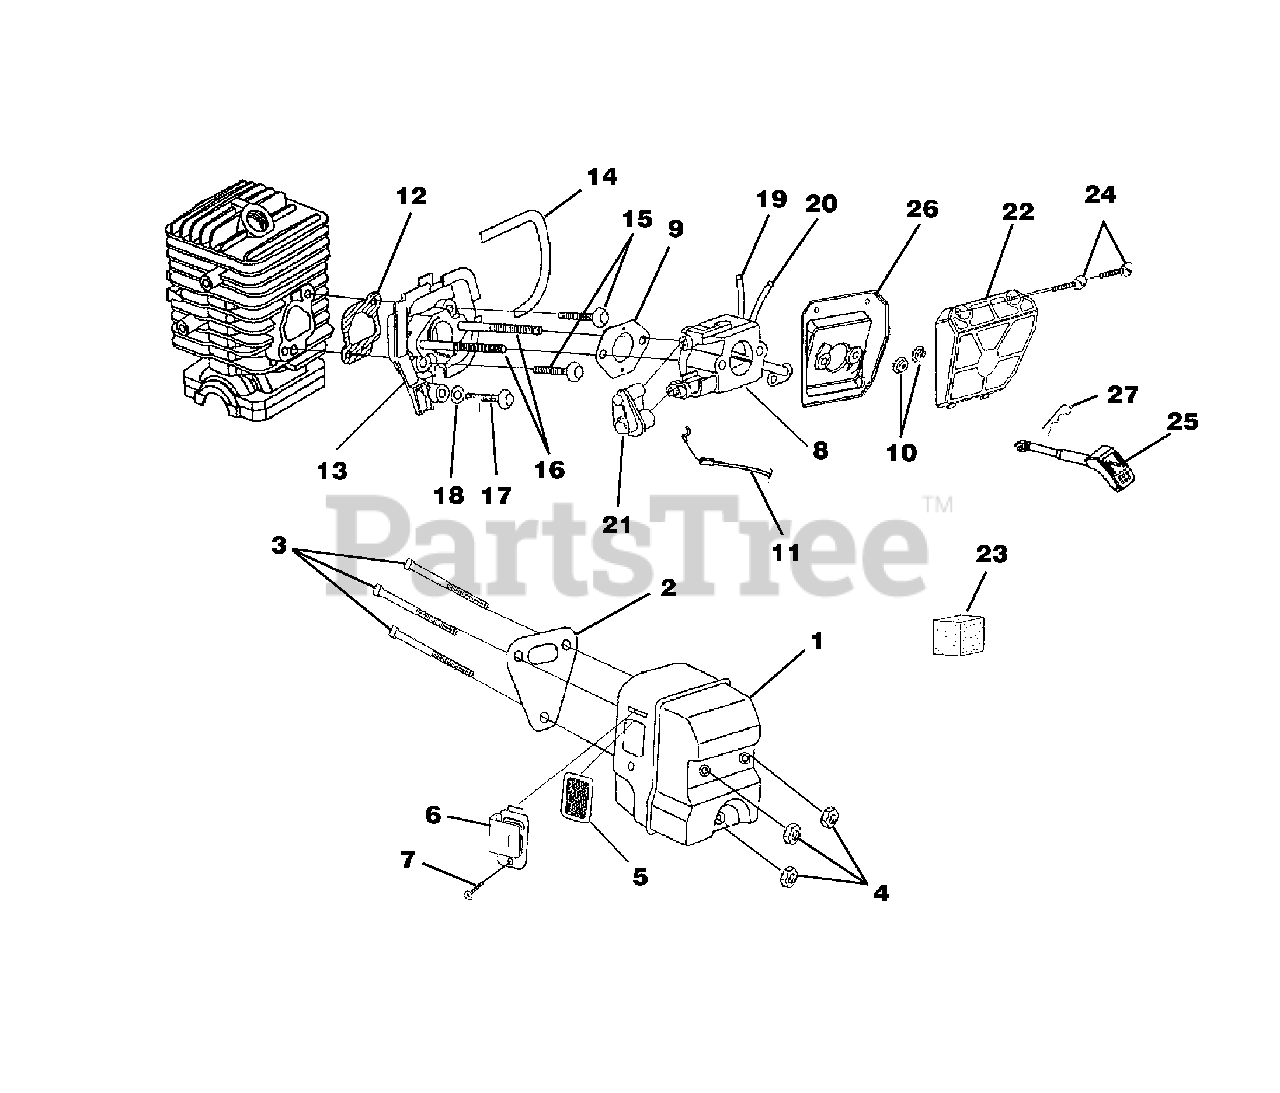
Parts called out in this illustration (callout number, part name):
1	Muffler Kit
2	Muffler Gasket
3	Screw-Square Hd.
4	Nut-Locking Hex (10-32)
5	Screen, Spark
6	Deflector, Muffler
7	Screw
8	Carburetor Assy
9	Carburetor Gasket
10	Flange Nut (10-24)
11	Throttle Cable
12	Gasket, Heat Dam
13	Heat Dam
14	Seal, Heat Dam
15	Screw, Truss Hd. Taptite (10-24 x 7/8")
16	Screw, Carburetor
17	Screw, Thread Form (10-14 x 1/2")
18	Washer, Retaining
19	Fuel Line (Tank to Carburetor 8 1/2")
20	Fuel Line (Carburetor to Purge Bulb 4")
21	Carburetor Grommet
22	Air Filter Cover
23	Pre Filter (In engine housing)
24	Screw-Slotted Pan Hd. (8-16 x 5/8")
25	Rod, Choke
26	Air Filter Plate
27	Spring Clip (Choke Rod)
